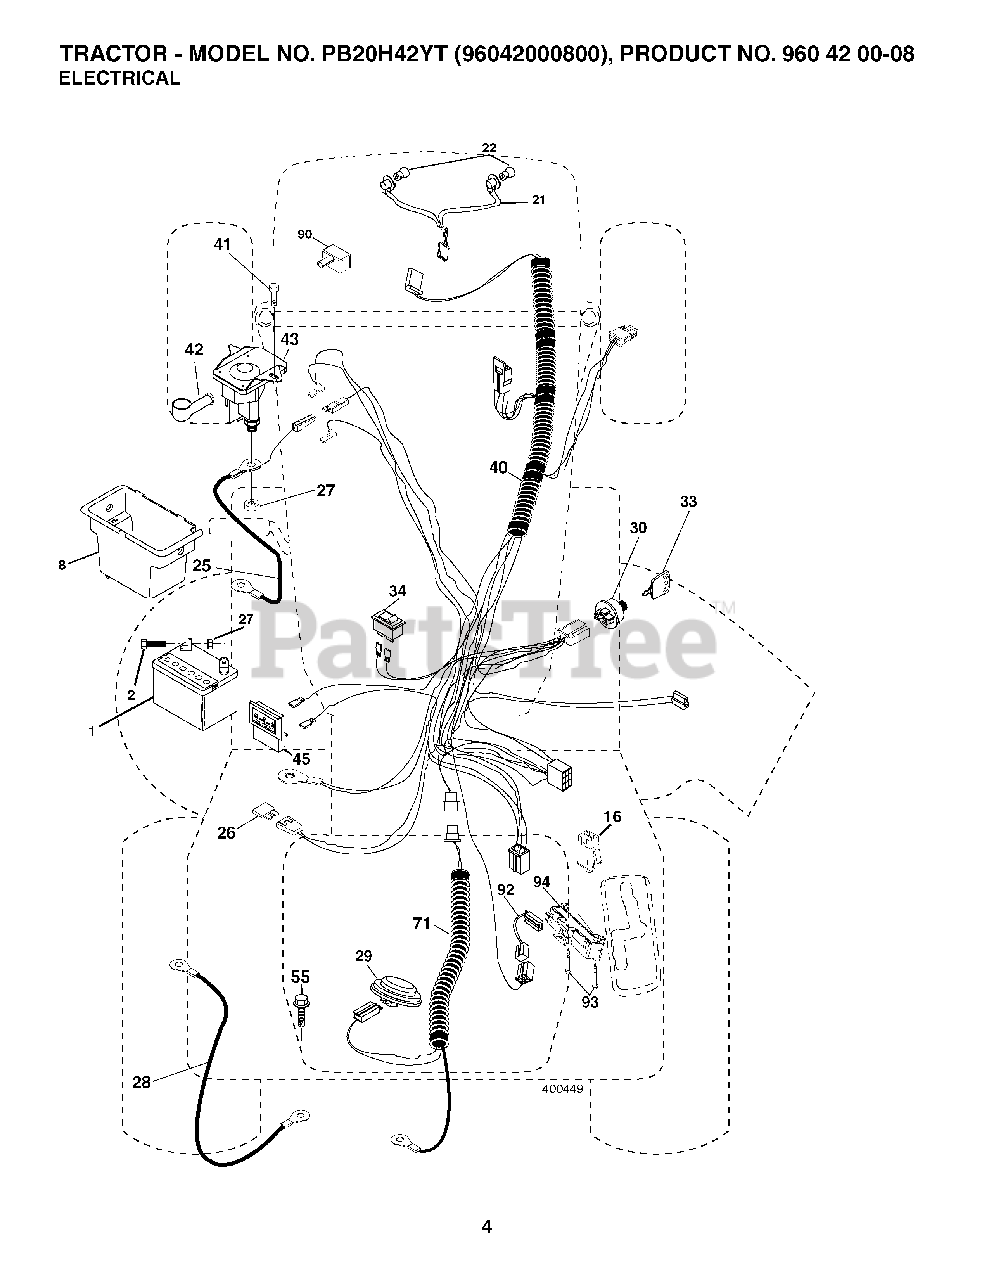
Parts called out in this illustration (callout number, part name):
1	Battery
2	Bolt Hex Head 1/4-20 x 3/4
8	Box Battery
16	Switch Interlock Push-In
21	Harness Socket Light W/4152J
22	Bulb Light
25	Cable Starter
26	Fuse
27	Nut Keps Hex 1/4-20 unc
28	Cable, Ground
29	Switch, Seat
30	Switch, Ign
33	Key, Ignition
34	Switch Light / Reset
40	Harness Ign.
41	Screw Thd Cut 1/4-20 x 1/2
42	Cover, Terminal
43	Solenoid
45	Ammeter
55	Screw Thdrol 5/16-18 x 3/4 TYTT
71	Harness Ign. Dash
90	Cover Terminal Battery
92	Harness Pigtail
93	Screw Plastite 10-14 x 2.0
94	Module Reverse ROS
